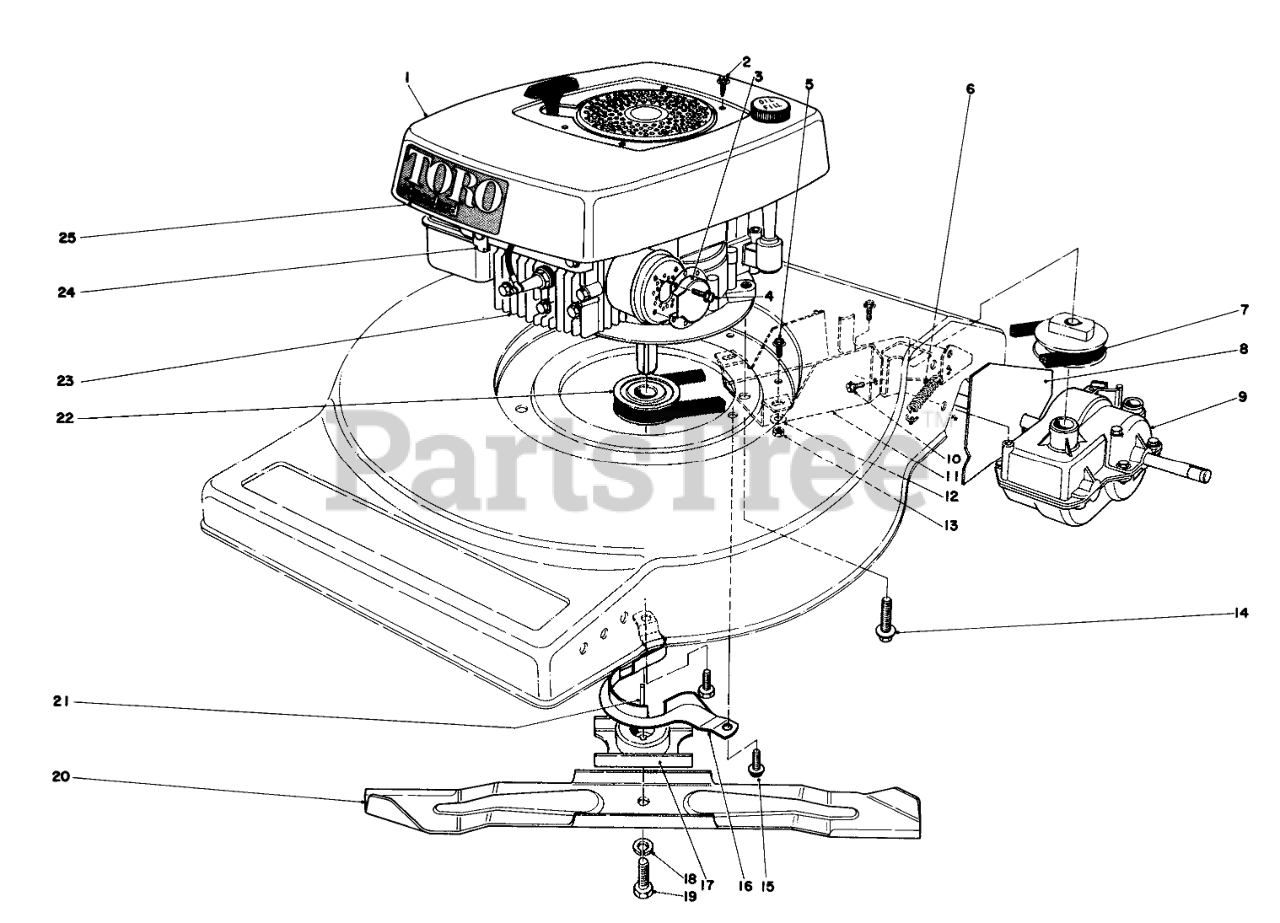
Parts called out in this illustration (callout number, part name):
1	SHROUD
2	8X1/2 SELF TAP SCREW
3	Deflector
4	SCREW W/ENGINE
5	SCREW-HWH
6	IDLER SPRING
7	V-BELT
8	GRASS SHIELD
9	Gear Case Assembly Complete
10	SCREW-HWHTF
11	COVER-BELT
12	WASHER-FLAT
13	Nut
14	SCREW-HWHTF
15	Screw
16	BELT GUIDE
17	Blade Retailer
18	WASHER-LOCK
19	SPECIAL SCREW
20	Blade
21	KEY-SQUARE
22	DRIVER PULLEY
23	Engine
24	Bracket Control
25	Decal Shroud
